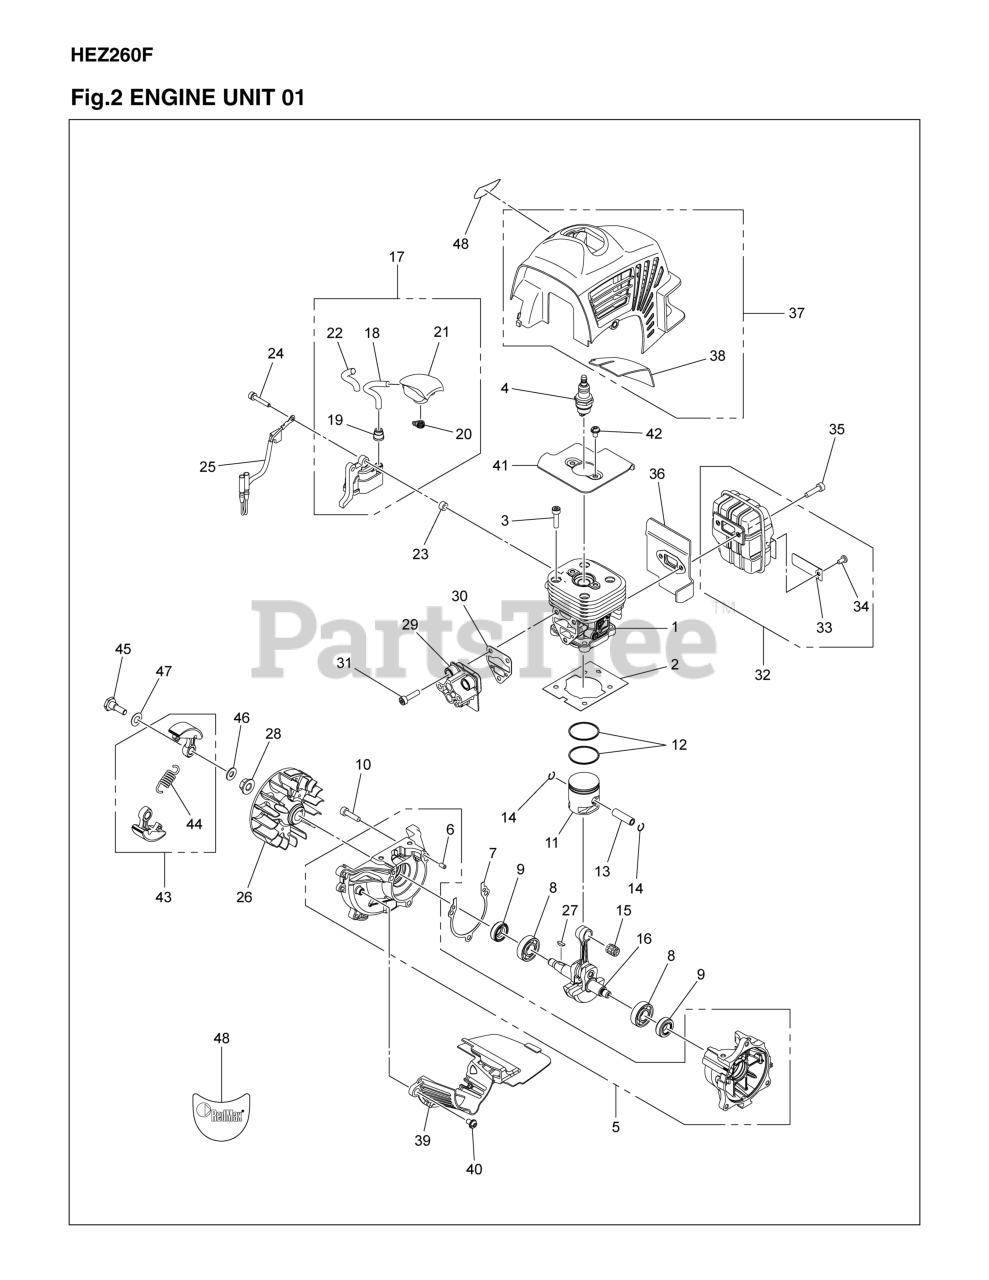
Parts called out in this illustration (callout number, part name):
1	CYLINDER COMP
2	GASKET BASE
4	SPARK PLUG, BPMR8Y
5	CRANKCASE ASSY
7	GASKET CASE
13	PIN
16	CRANKSHAFT COMP
17	IGNITION COIL,ASSY
18	IGNITION CABLE
19	HUB CAP 848F6L71E0
21	SPARK PLUG CAP
22	TUBE (RPLS 263072210)
24	BOLT M4 X 25
25	SHORT CIRCUIT CABLE
26	FLYWHEEL
27	KEY
28	NUT
29	INSULATOR
32	MUFFLER ASSY
33	SPARK ARRESTER
34	SCREW CRPANT TYPE F ST4.2X9.5
36	GASKET MUFFLER
37	CYLINDER COVER COMP
38	SHEET HEAT INSULATION
39	PLATE MUFFLER
41	PLATE CYLINDER
43	CLUTCH ASSY
44	CLUTCH SPRING
48	DECAL BRAND
